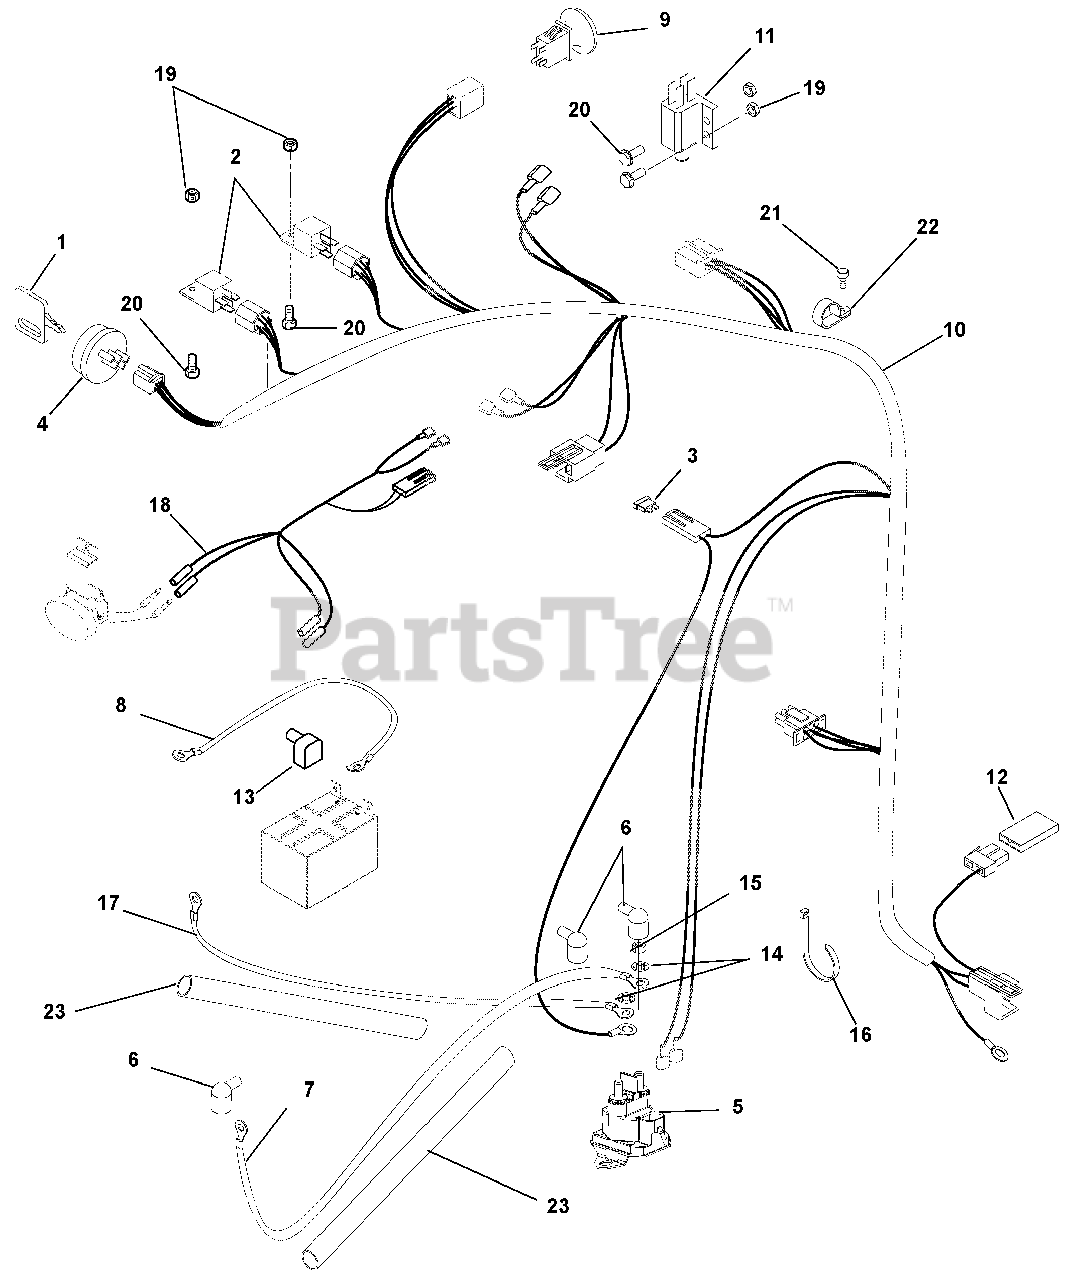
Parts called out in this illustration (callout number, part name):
1	KEY -W/CAP
2	RELAY
3	FUSE-25 AMP ATC TYPE
4	KEY SWITCH
5	SOLENOID, STARTER (SEALED)
6	BOOT, EYELET TERMINAL
7	CABLE,POS W/2 1/4 RING 18.5 LG
8	CABLE-GROUND .25 X 13.00 X .31
9	SWITCH, CLUTCH
10	HARNESS, ZOOMXL/ZTXL WIRE
11	SWITCH- DOUBLE POLE N.O./N.O.
12	DIODE, CONNECTOR SHELL
13	INSULATOR
14	WSHR-LOCK INT .31 YWZC
15	NUT-JAM .31-24 YWZC
16	CABLE TIE LG 5-1/2
17	CABLE,POS W/2 1/4 RING 18.5 LG
18	HARNESS, XL HEADLIGHT
19	@NUT-LK-NYL 10-24 W/INSRT YWZC
20	@SCR-MCH 10-24X.75 HWH YWZC
21	@SCR-TAP .38-16X.50 HWH TR YWZ
22	CLAMP, CUSHIONED STEEL .75
23	SLEEVE, ANTI-ABRASION
